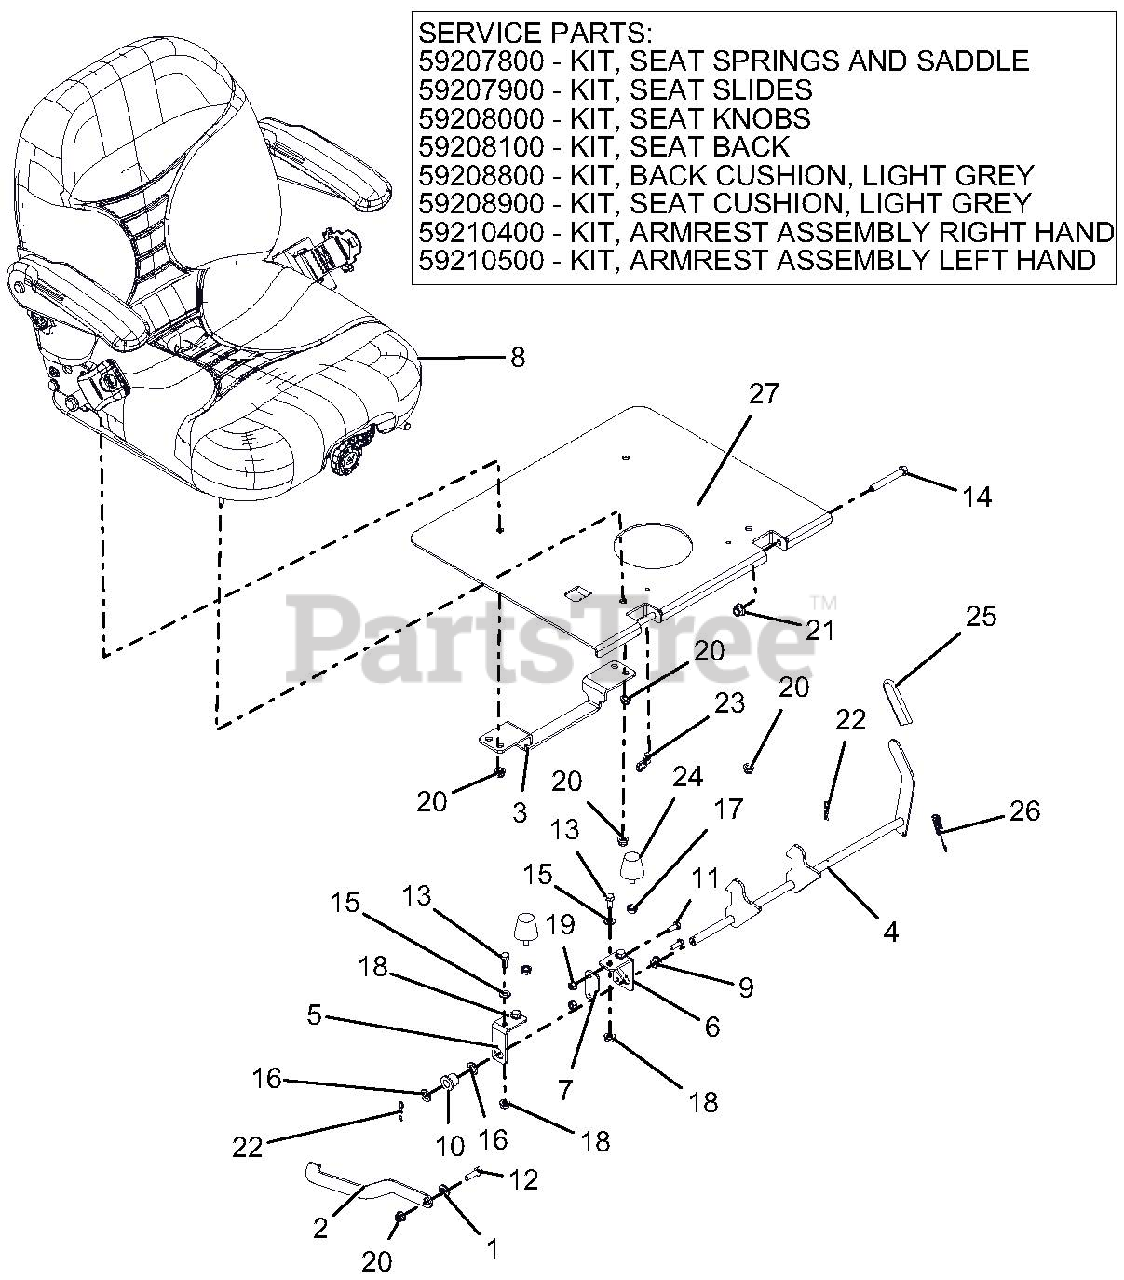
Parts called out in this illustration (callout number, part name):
1	BSHG, FLG .325X.499X.26X.88
2	STOP, SEAT
3	BRKT, SEAT LATCH
4	WMT, SEAT LATCH
5	MOUNT, SEAT LATCH - RH
6	MOUNT, SEAT LATCH - LH
7	RETAINER-SEAT LATCH
8	SEAT, SUSPENSION W/SEAT BELT, LT GRAY
9	BUSHING, POLYLINER - .50 SPLIT
10	BSHG, FLANGE .515 X .750 X .745 X 1.00 NYLON
11	BLT-HEX .25-20X.75 GR5 YWZC
12	BLT-HEX .31-18X1.00 GR5 YWZC
13	BLT-HEX .31-18X.75 GR5 YWZC
14	BLT-HEX .38-16X2.75 GR5 YWZC
15	WSHR-FL-STL.344X.688X.065YWZC
16	WSHR-FL-STL .520X.827X.062 YWZC
17	@NUT-SPNLK-FLG .312-18 YWZC
18	NUT, LK-TOP-FLG .312-18 YWZC
19	NUT, LK-TOP-FLG .25-20 YWZC
20	NUT-LK-NYL-FLG .31-18 YWZC
21	NUT-LK-NYL-FLG .38-16 YWZC
22	PIN-HAIR INT .08X.38X1.42 YWZC
23	CABLE TIE W/ TREE (.25 HOLE)
24	BUMPER, RUBBER CONE STUD MOUNT
25	GRIP-VINYL-YELLOW .125 x 1.0 x 3.0
26	SPRG, EXTENSION
27	SEAT, PLATE WLDMT W/SAFETY DECALS
28	KIT SEAT SPRINGS AND SADDLE
29	KIT SEAT SLIDES
30	KIT SEAT KNOBS
31	KIT SEAT BACK
32	KIT BACK CUSHION, LIGHT GREY
33	KIT SEAT CUSHION, LIGHT GREY
34	KIT ARMREST ASSEMBLY RIGHT HAND
35	KIT ARMREST ASSEMBLY LEFT HAND
